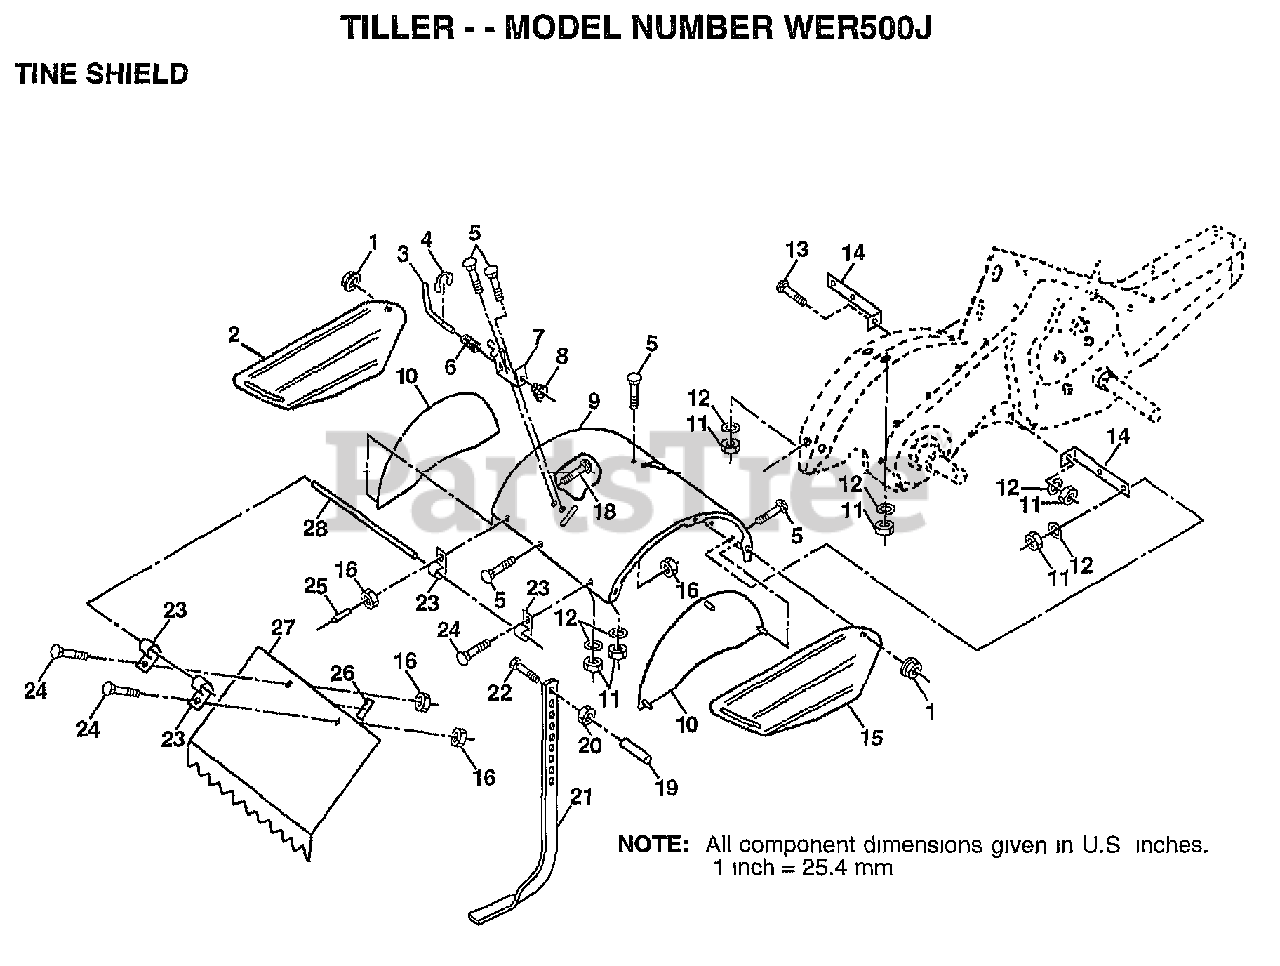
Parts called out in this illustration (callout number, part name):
1	NUT
2	SHIELD.SIDE.OUTER.LH
3	STAKE PIN TI
4	KLIP RING TI
5	BOLT
6	SPRING TI
7	LATCH BRACKET TI
8	SPRING CRT
9	SHIELD.TINE.PNT.
10	SHIELD.SD.INNER
11	NUT.HEX.5/16-18
12	LOCKWASHER
13	BOLT
14	BRKT SHIELD TINE
15	SHIELD.SIDE.OUTER.RH
16	NUT
18	BOLT
19	GRIP CRT
20	NUT.HEX.3/8-16UNC
22	BOLT
23	HINGE CRT
24	BOLT
25	VINYL CAP TI
26	PAD IDLER TI
27	SHIELD.LEVELING
28	PIN HINGE
